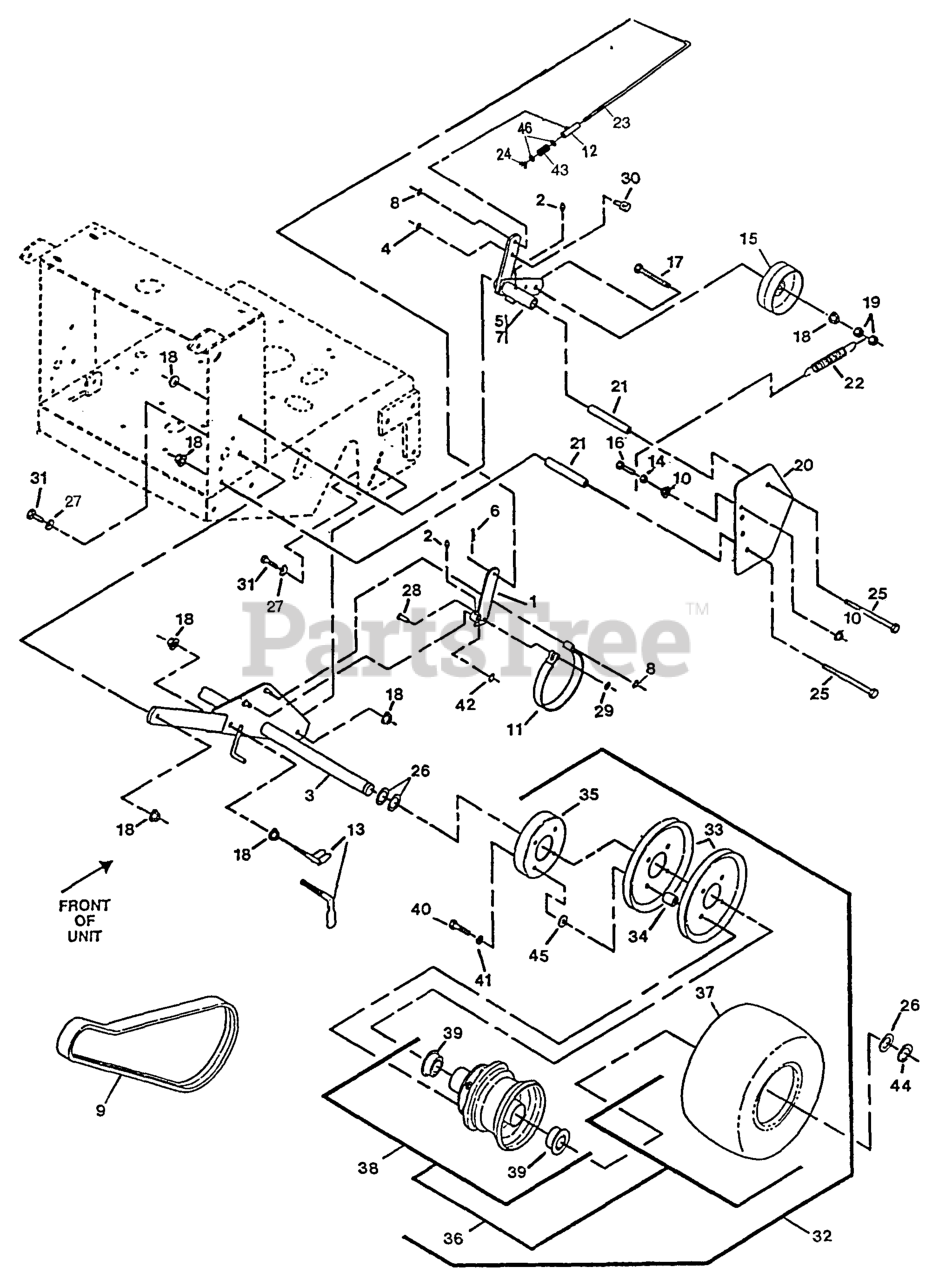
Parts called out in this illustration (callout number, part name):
3	AXLE
6	PIN-COTTER
9	BELT,WHEEL DRIVE
11	BAND-BRAKE
13	SCRAPER
15	IDLER-WHEEL, DRIVE
20	SHIELD-WHEEL, DRIVE
21	SPACER-SHIELD
22	SPRING-EXTENSION
23	LINKAGE-BRAKE
24	WINGNUT-NYLOCK
26	WASHER-SPACER
28	PIN-CLEVIS
29	RING-RETAIN,PUSH,EXT,FLAT
30	SWIVEL-SHORT, ADJUSTABLE
33	SHEAVE-WHEEL, DRIVE
34	SPACER-SHEAVE, WHEEL
35	DRUM-BRAKE
36	WHEEL AND TIRE ASM
37	TIRE-TURFMASTER
38	WHEEL AND HUB ASM
39	BEARING-FLANGED
41	WASHER-LOCK
43	SPRING-COMPRESSION
44	RING-SNAP
45	WASHER
